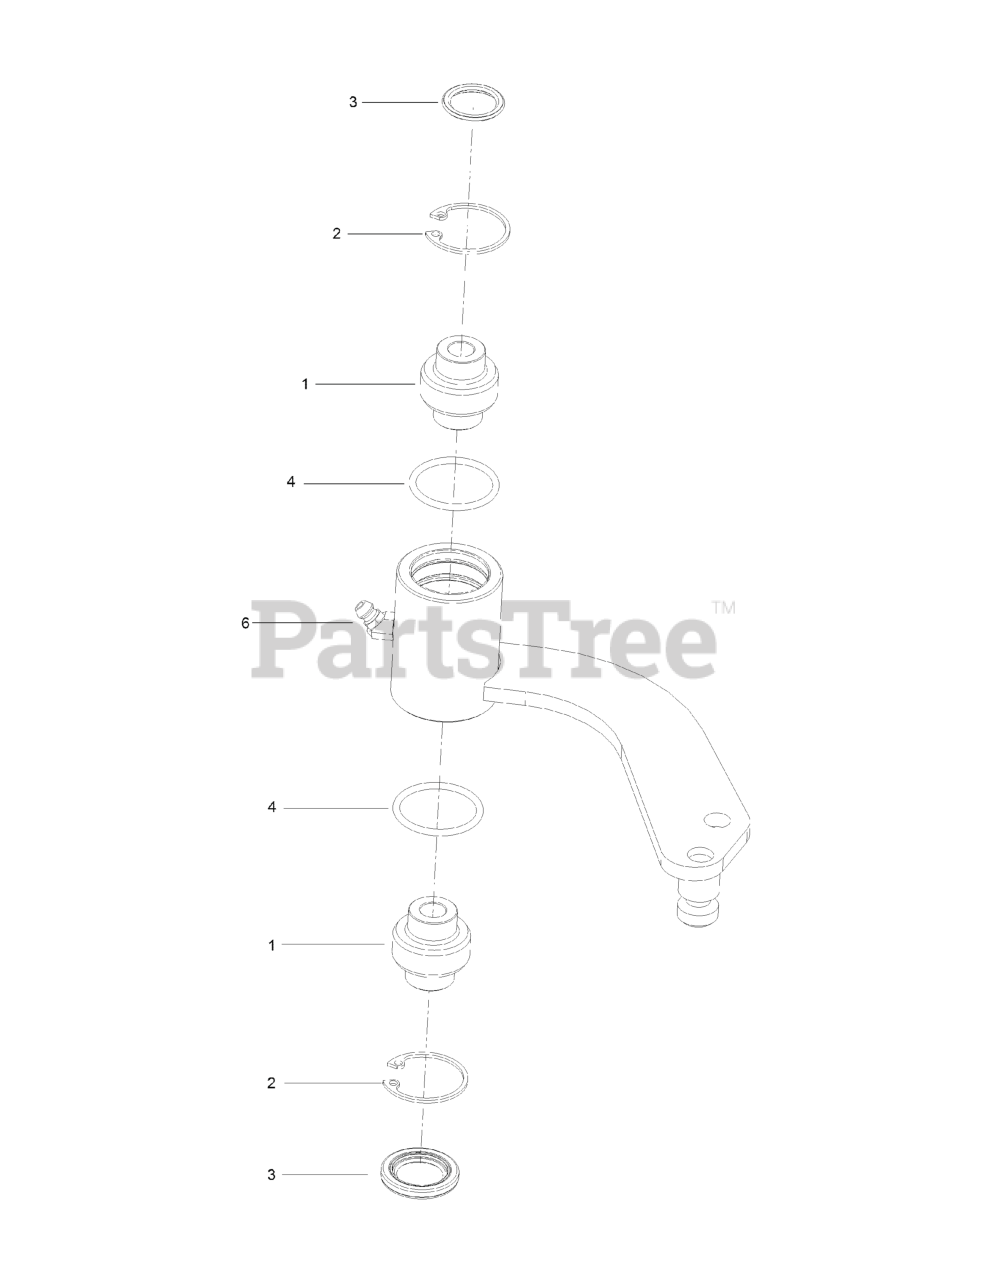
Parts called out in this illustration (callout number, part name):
1	BEARING-SPHERICAL
2	RING-SNAP
3	SEAL-LIP, SINGLE
6	FITTING-LUBE, 45 DEG
